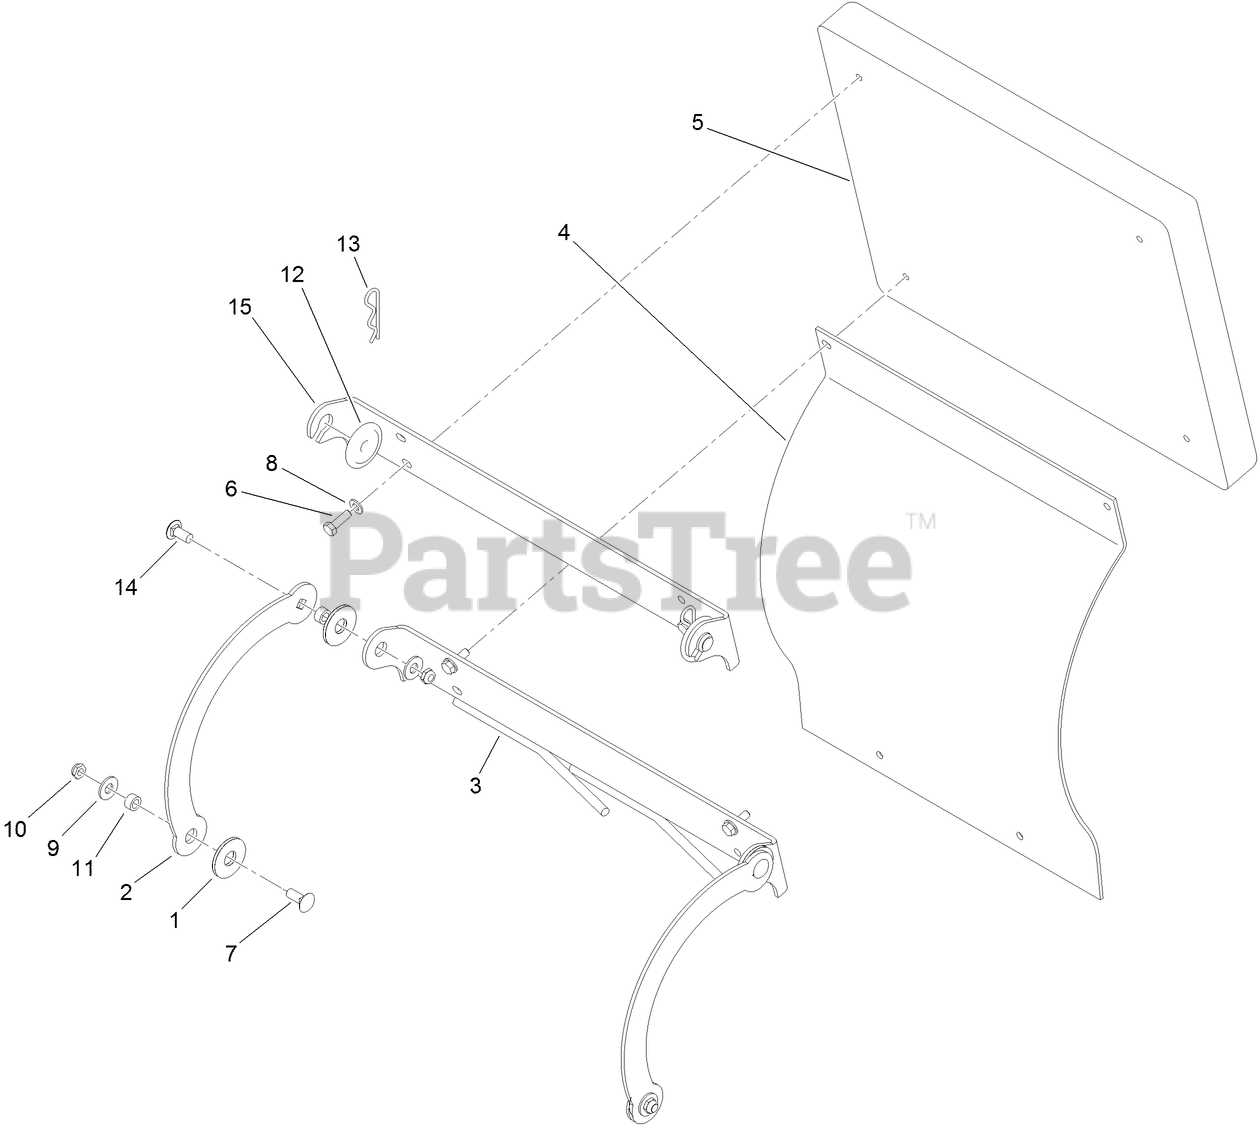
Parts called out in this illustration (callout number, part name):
1	WASHER-FRICTION, COMPOSITE
2	LINK-PAD
3	HINGE-LOWER
4	SHIELD-REAR
5	PAD-CUSHION
6	SCREW-HH
7	BOLT-CARR
8	WASHER-PLAIN
9	WASHER-FLAT
10	NUT-LOCK, NI
11	SPACER
12	SLIDE-BUSHING
13	PIN-HAIR
14	SCREW-CARR
15	HINGE-PAD
